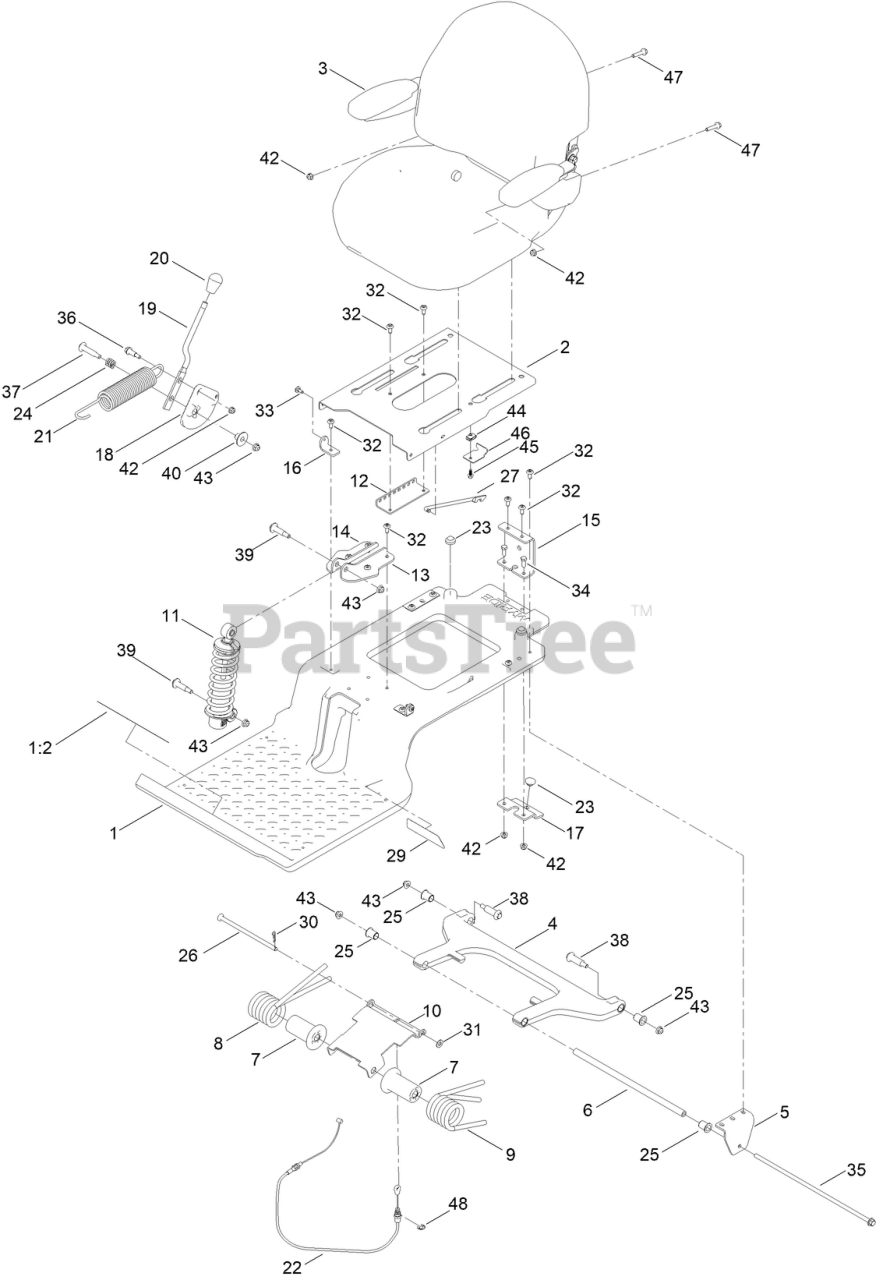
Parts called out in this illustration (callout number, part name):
1	SUBFRAME ASM
1:2	DECAL-DANGER
2	PAN-SEAT
3	SEAT ASM
4	ARM, SWING
5	BRACKET-MOUNT, SWING ARM
6	TUBE-SPACER
7	RETAINER-SPRING
8	SPRING-TORSION, RH
9	SPRING-TORSION, LH
10	PLATE-ADJUSTER
11	SHOCK/SPRING ASM
12	BRACKET-LATCH, SEAT
13	BRACKET-SHOCK MOUNT, UPPER (LH)
14	BRACKET-SHOCK MOUNT, UPPER (RH)
15	BRACKET-CABLE
16	BRACKET-SEAT
17	BRACKET LOWER
18	PULLEY - CAM
19	LEVER - ADJUSTMENT
20	KNOB-MR
21	SPRING-EXTENSION
22	CABLE-ADJUSTMENT, MYRIDE
23	BUMPER-SEAT
24	SPRING-COMPRESSION
25	BUSHING-FLANGE
26	ROD-ADJUSTMENT
27	ROD-PROP, SEAT
29	DECAL-MYRIDE
30	PIN-COTTER
31	WASHER-FLAT
33	SCREW-SHOULDER
34	SCREW-HH
35	SCREW-HHF
36	BOLT-SHOULDER, HHF
37	BOLT-SHOULDER
38	BOLT-SHOULDER
39	BOLT-SHOULDER
40	BUSHING - FLANGE
42	NUT-HF, NI
43	NUT-HF, NI
45	SCREW-HHF
46	BRACKET-STOP, SEAT
47	SCREW-HHF
48	RING-RETAINING, EXTERNAL
